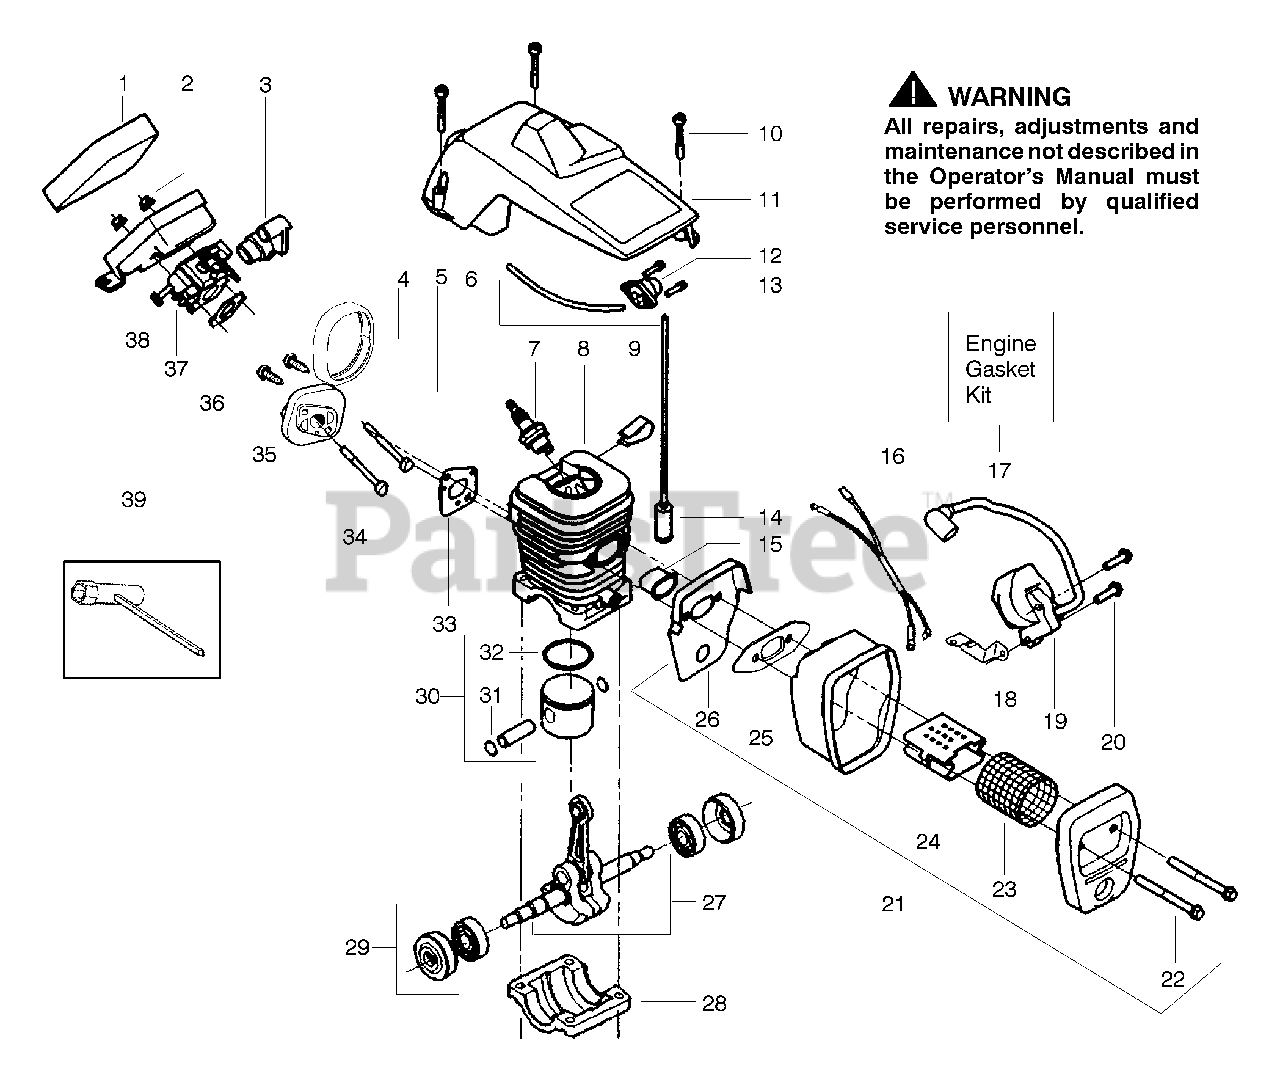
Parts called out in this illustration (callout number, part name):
1	Foam Air Filter
3	Grommet Carb Adjust
4	Seal Carb Adapter
5	Adapter Carb.
6	Kit Fuel Line (Small)
7	Spark Plug (RCJ 7Y)
8	Kit Cylinder
9	Clip High Tension Lead
11	Shield Cylinder
12	Assy Air Purge
14	Assy Fuel Pick up
15	Insulator Heat
16	Assy. Wire Harness
17	Kit Engine Gasket
18	Strap Ground
19	Module Ignition
21	Assy Muffler
23	Screen Spark
24	Diffuser Muffler
25	Gasket Muffler(kit)
26	Backplate Muffler
27	Assy. Crankshaft
28	Cap Crankcase
29	Assy.Seal & Bearing
30	Kit Piston
31	Retainer Piston Pin
32	Ring Piston
33	Gasket Adapter(kit)
36	Gasket Carb.(kit)
37	Kit Carburetor (W-14A)
38	Housing Air Filter
39	Wrench Bar
